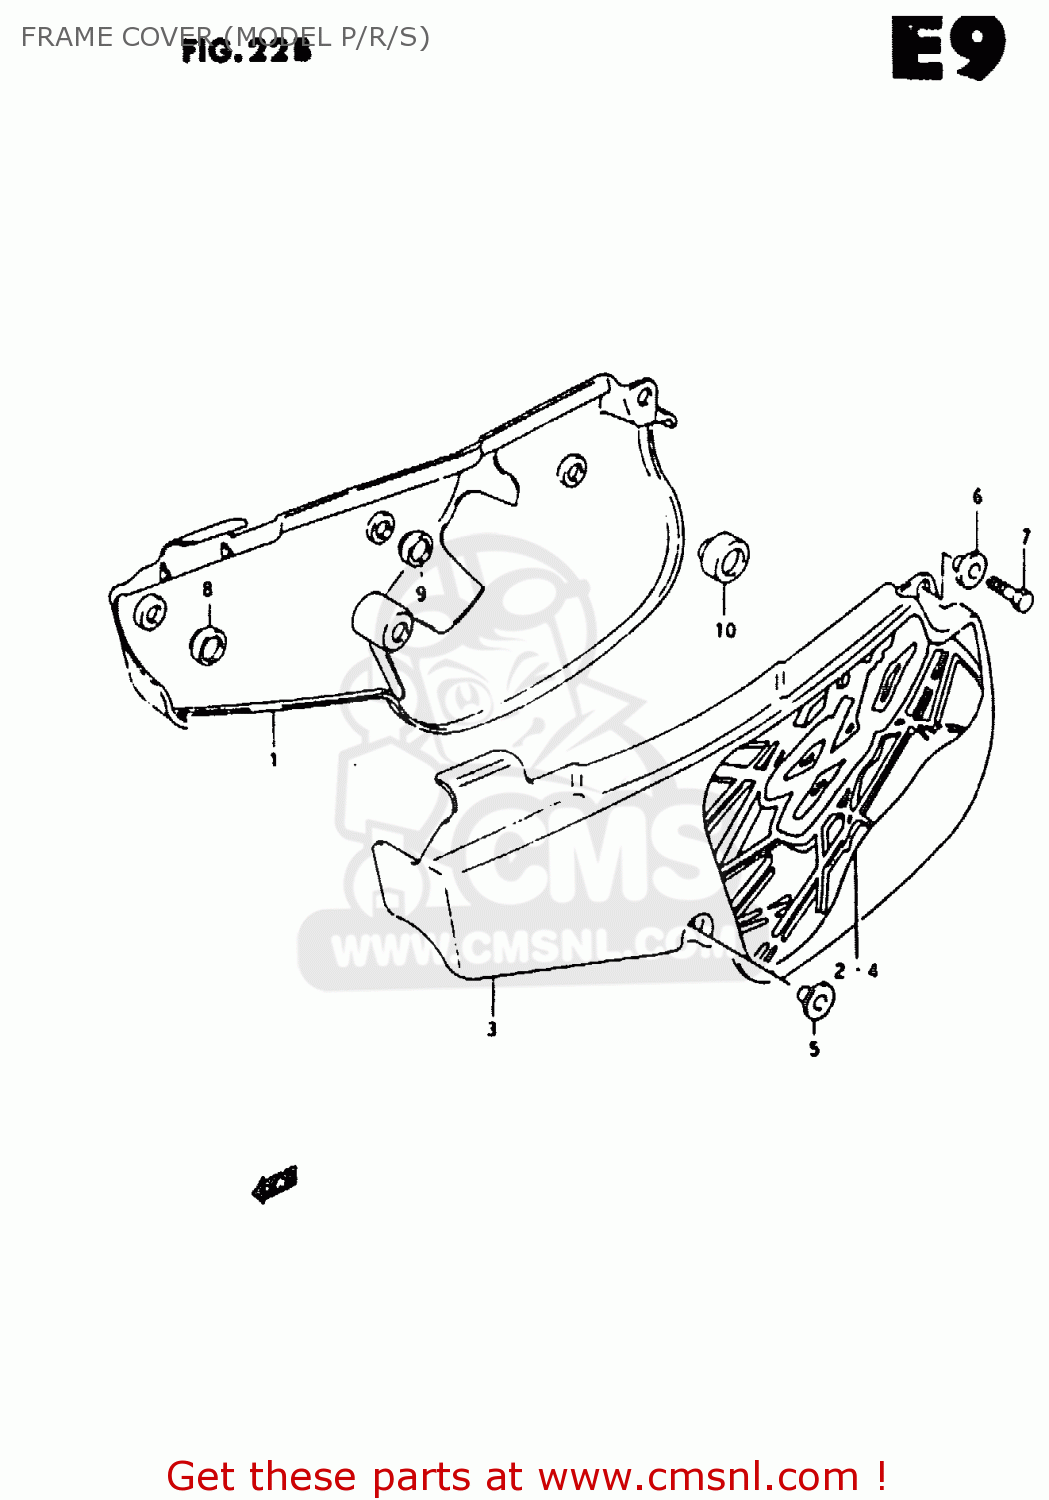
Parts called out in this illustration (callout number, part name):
1	COVER,SIDE,R(WHITE)
2	EMBLEM,FRAME COVER,RIGHT
3	COVER,SIDE,L(WHITE)
4	EMBLEM,FRAME COVER,LEFT
5	WASHER
6	WASHER
7	BOLT
8	CUSHION
9	WASHER
10	WASHER
11	BOLT
12	CUSHION
13	CUSHION
14	CUSHION
15	CUSHION
